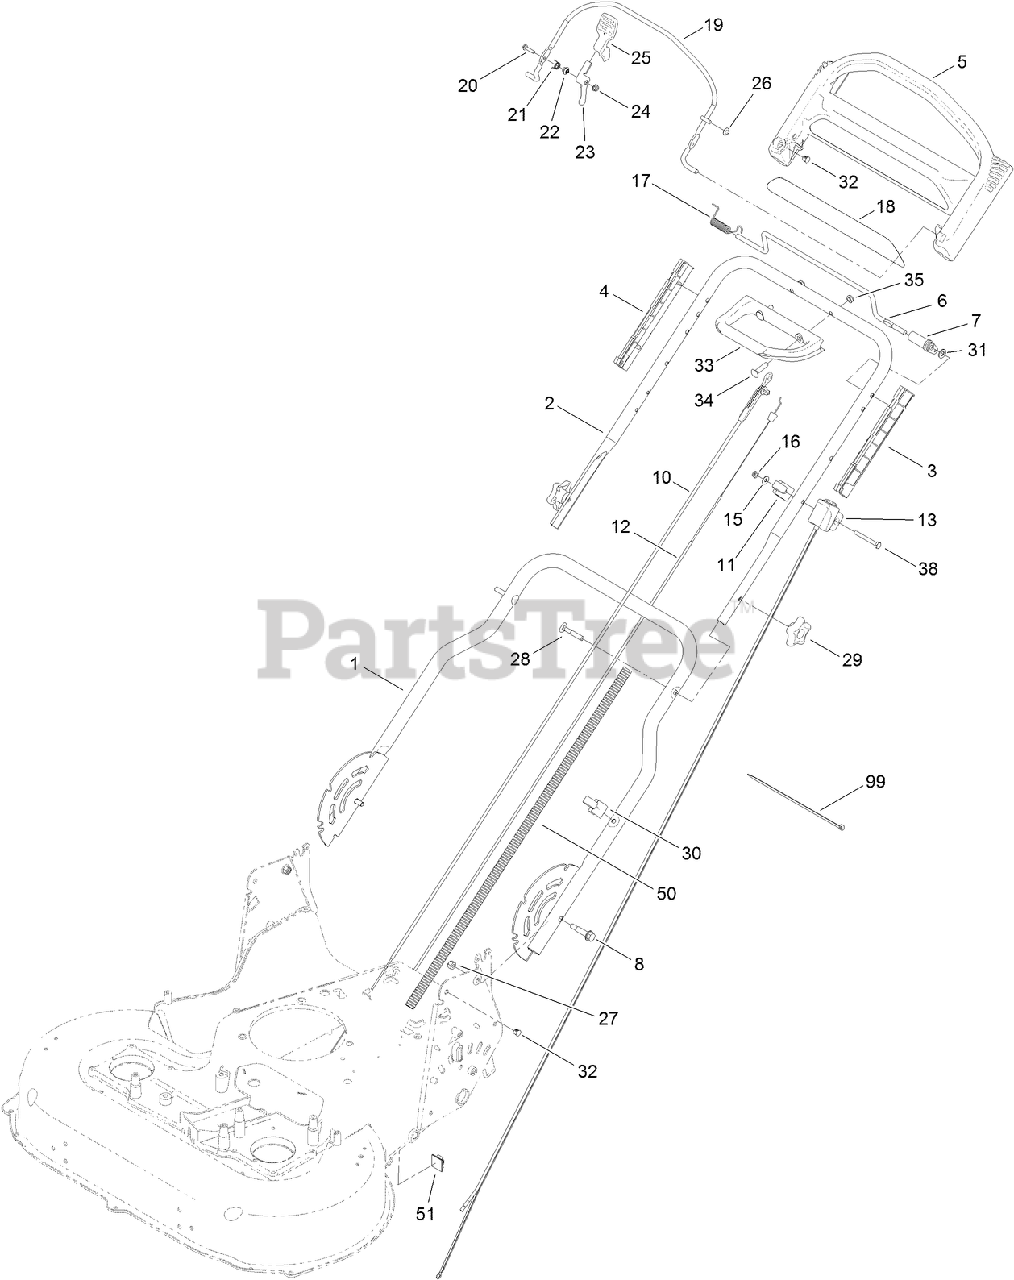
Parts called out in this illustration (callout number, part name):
1	HANDLE-LOWER
2	HANDLE-UPPER
3	GUIDE-LH
4	GUIDE-RH
5	HANDLE-CONTROL
6	BAR-CONTROL, TRACTION
7	LEVER-TRACTION
8	BOLT-SHOULDER, HHF
10	CABLE-BRAKE, BBC
11	ANCHOR-CABLE
12	CABLE-TRACTION
13	SWITCH HOUSING ASM
15	WASHER-FLAT
16	NUT-LOCK, NI
17	Spring-Torsion
19	BAIL-BRAKE
20	SCREW-HWH
21	SPRING-TORSION
22	SPACER
23	LEVER
24	NUT-LOCK, FLANGE
26	NUT-SPEED
27	NUT-LOCK, NI
28	SCREW-HANDLE
29	KNOB-HANDLE
30	GUIDE-CABLE
31	WASHER-PLAIN
32	Plug-Dome
33	HANDLE-ASSIST, TRACTION
34	BOLT-CARRIAGE
35	NUT-LOCK, NI
38	SCREW-HH
50	CONDUIT-CONVOLUTED
51	GUIDE-CABLE
99	TIE-CABLE
